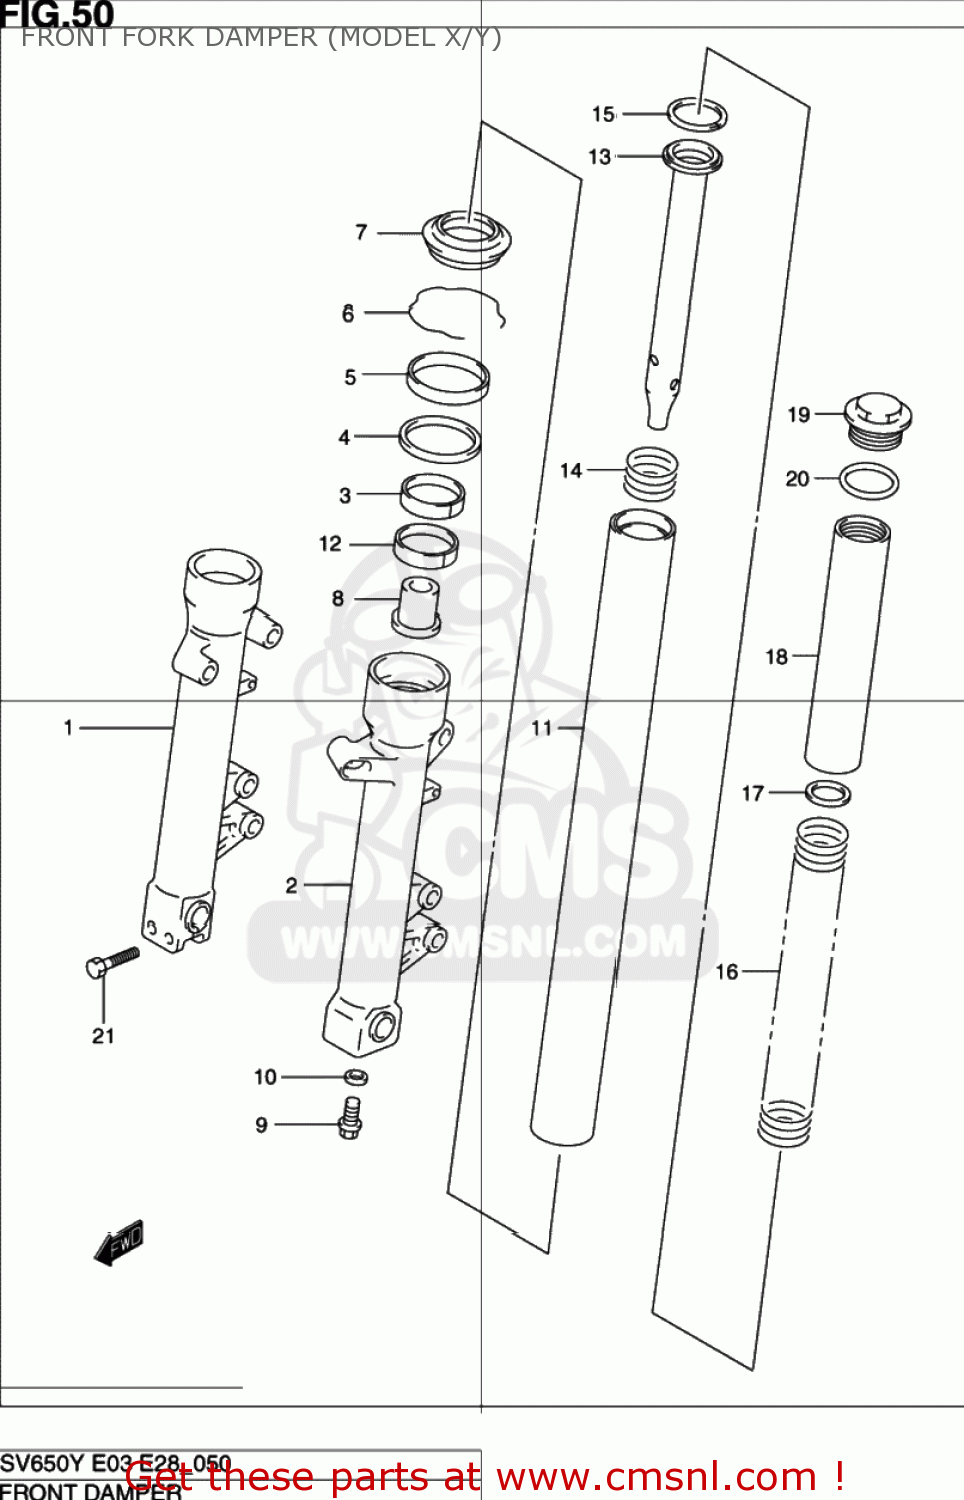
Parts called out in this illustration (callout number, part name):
1	TUBE,OUTER,R
2	TUBE,OUTER,LEFT
3	METAL,SLIDE
4	WASHER,FORK OIL SEAL
5	SEAL,OIL
6	RING,OIL SEAL STOPPER
7	SEAL,DUST
8	PIECE,OIL LOCK
9	BOLT,FORK CYLINDER(10X25)
10	GASKET (NAS)
11	TUBE,INNER
12	PISTON
13	CYLINDER
14	SPRING,REBOUND
15	RING,PISTON
16	SPRING,FR
17	WASHER(22.5X35.9X1.6)
18	SPACER,SPRING
19	CAP,OUTER TUBE
20	O RING(D:3.5,ID:31.7)
21	BOLT
